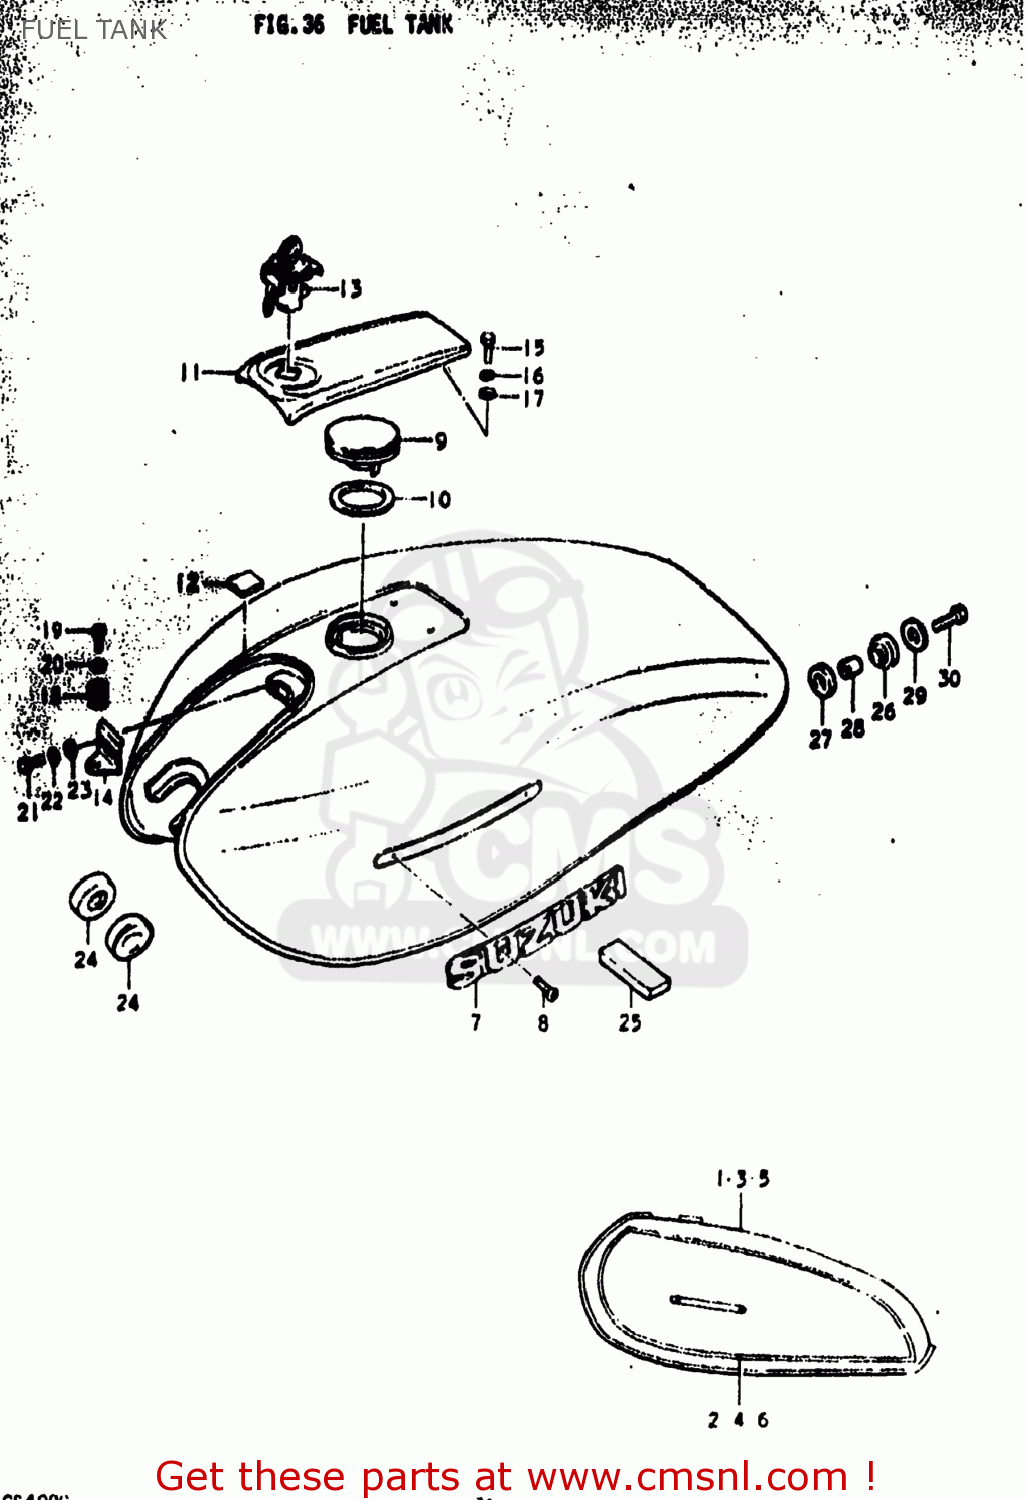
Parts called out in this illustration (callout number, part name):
1	TANK ASSEMBLY,FUEL
3	TANK ASSEMBLY,FUEL
5	TANK ASSEMBLY,FUEL
7	EMBLEM,FUEL TANK
8	SCREW
9	CAP,FUEL TANK
10	GASKET (NAS)
11	COVER,FUEL TANK
12	CUSHION,FUEL TANK FR COVER
13	LOCK,FUEL TANK FR COVER
14	HOLDER,FUEL TANK FRONT COVER
15	BOLT
16	LOCK WASHER
17	WASHER
18	SPRING
19	SCREW
20	LOCK WASHER
21	BOLT
22	LOCK WASHER
23	WASHER 5MM
24	CUSHION
25	CUSHION
26	CUSHION
27	CUSHION
28	SPACER(8.5X12X19)
29	WASHER (8.5X29X1.6)
30	BOLT (8X30)
